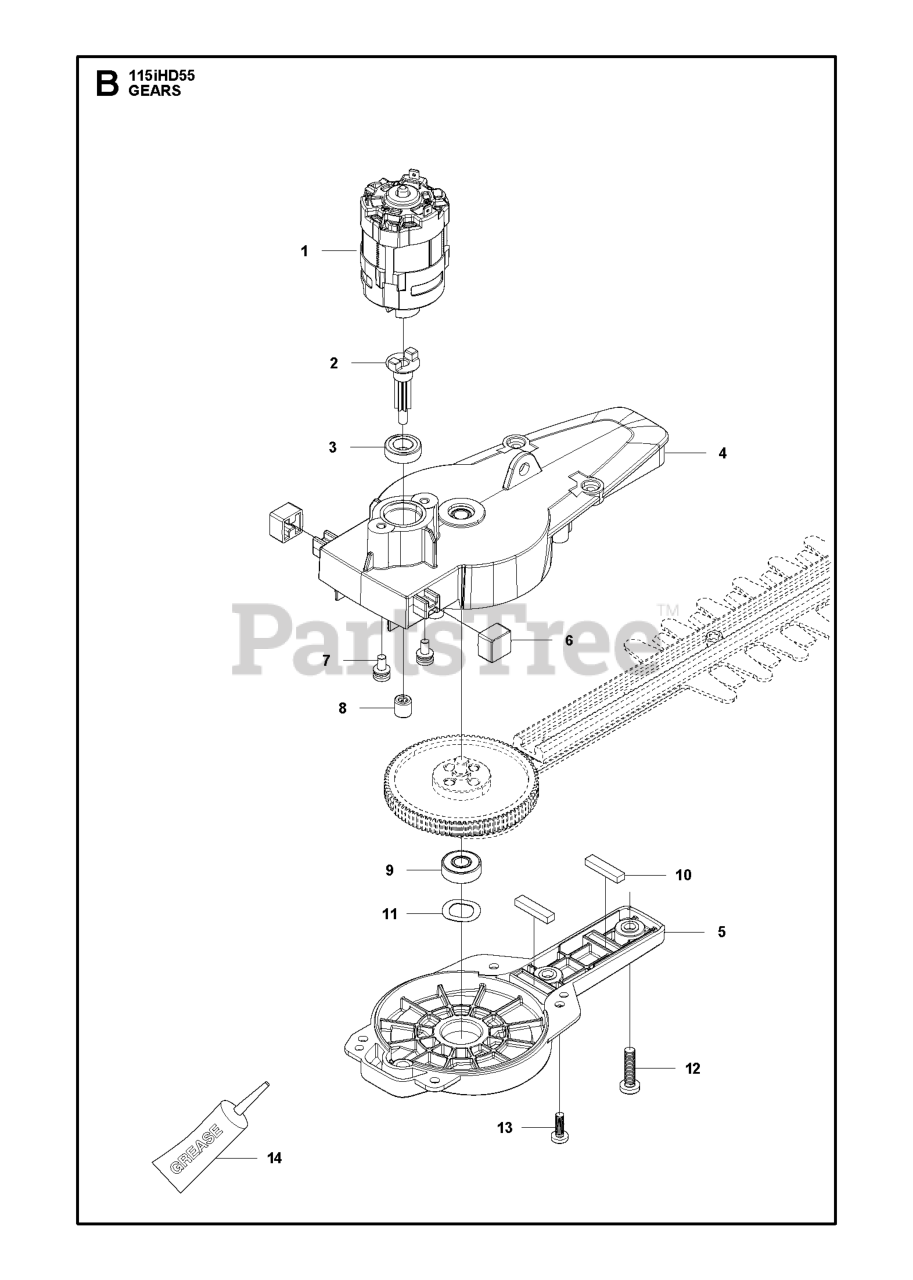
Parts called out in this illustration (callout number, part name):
1	MOTOR ASSEMBLY
3	BALL BEARING 689 2RS
4	GEAR BOX ASSEMBLY
5	COVER GEAR BOX
6	SHOCK ABSORBING
7	SCREW M3X10
8	NEEDLE BEARING
9	BALL BEARING
10	PAD DUSTPROOF
11	SPRING WASHER
12	SCREW M5X20
13	SCREW M4X12
14	GREASE
